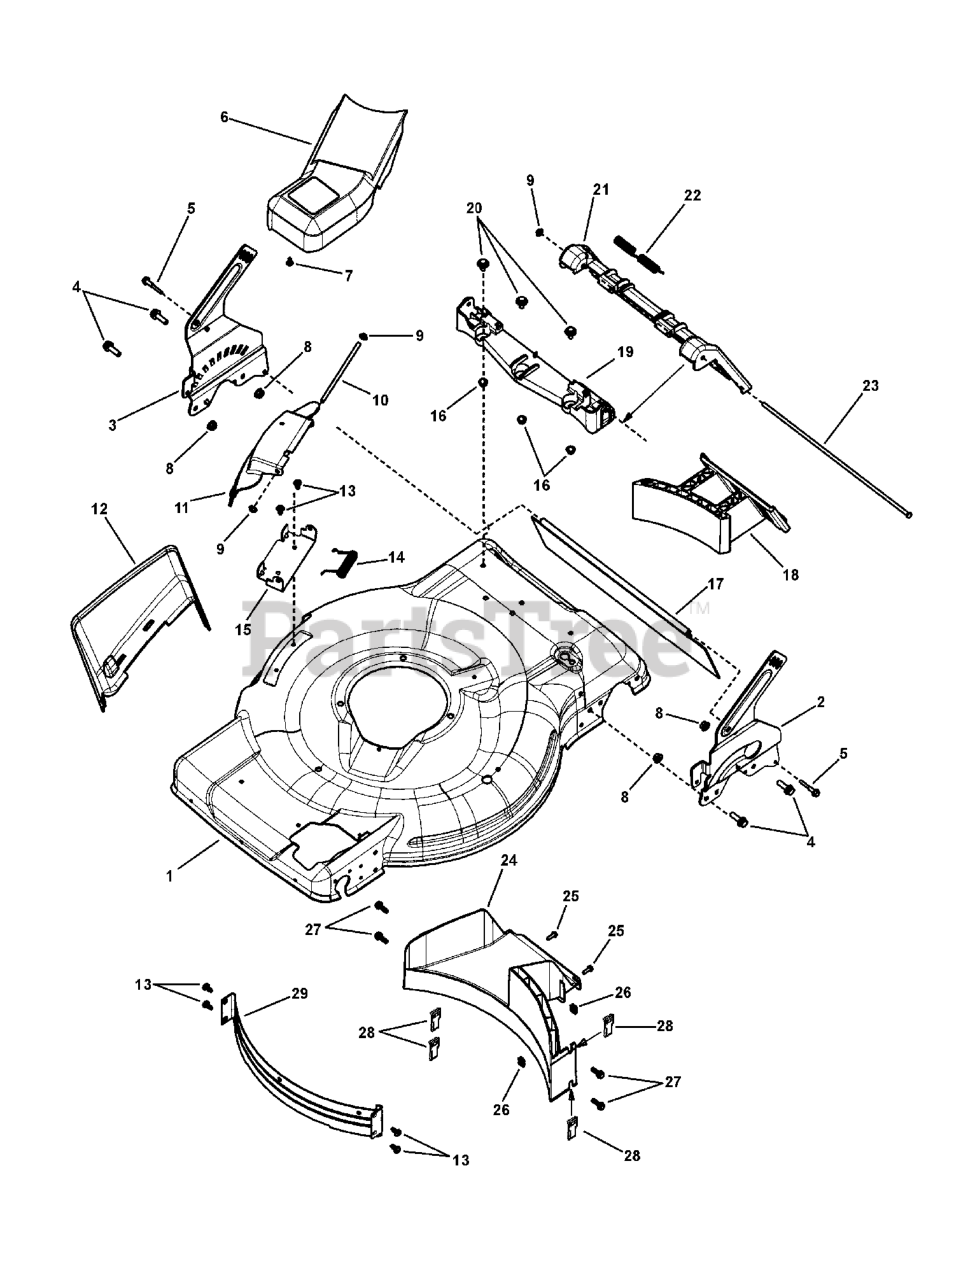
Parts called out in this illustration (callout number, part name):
1	DECK, 22"
2	BRKT, REAR WHEEL, LH, QUICK ADJUST
3	BRKT, REAR WHEEL, RH, QUICK ADJUST
4	HFLB, 5/16-18 X 1 YZ
5	BOLT, DRAG SHIELD, 1/4 - 20 X 1.5
6	COVER, BELT DRIVE, FRONT
7	SCREW, ROUND WASHER HEAD TORX, HI-LO
8	FLN, 5/16-18 YZ
9	PUSHNUT 1/4
10	ROD, PIVOT
11	COVER, MULCHING
12	CHUTE, SIDE DISCHARGE, WBM, 22"
13	TORX ST, 1/4-20 X .550
14	SPRING, TORSION, CHUTE
15	BRACKET, CHUTE
16	HFLN, 1/4-20
17	GUARD, REAR 22"
18	PLUG, MULCHING, 22" DECK
19	REAR DISCHARGE DOOR HINGE
20	HHSTS, 1/4-20 x 5/8"
21	REAR DISCHARGE DOOR
22	SPRING, TORSION, REAR DOOR
23	ROD, PIVOT, REAR DOOR
24	REAR BAFFLE, FRONT WHEEL DRIVE, WBM
25	HWFST,10C X 5/8
26	NUT, RETAINER SPEED #10C W/EXT
27	HFLB, 1/4-20X3/4
28	NUT, 1/4 TINNERMAN
29	BAFFLE, FRONT
